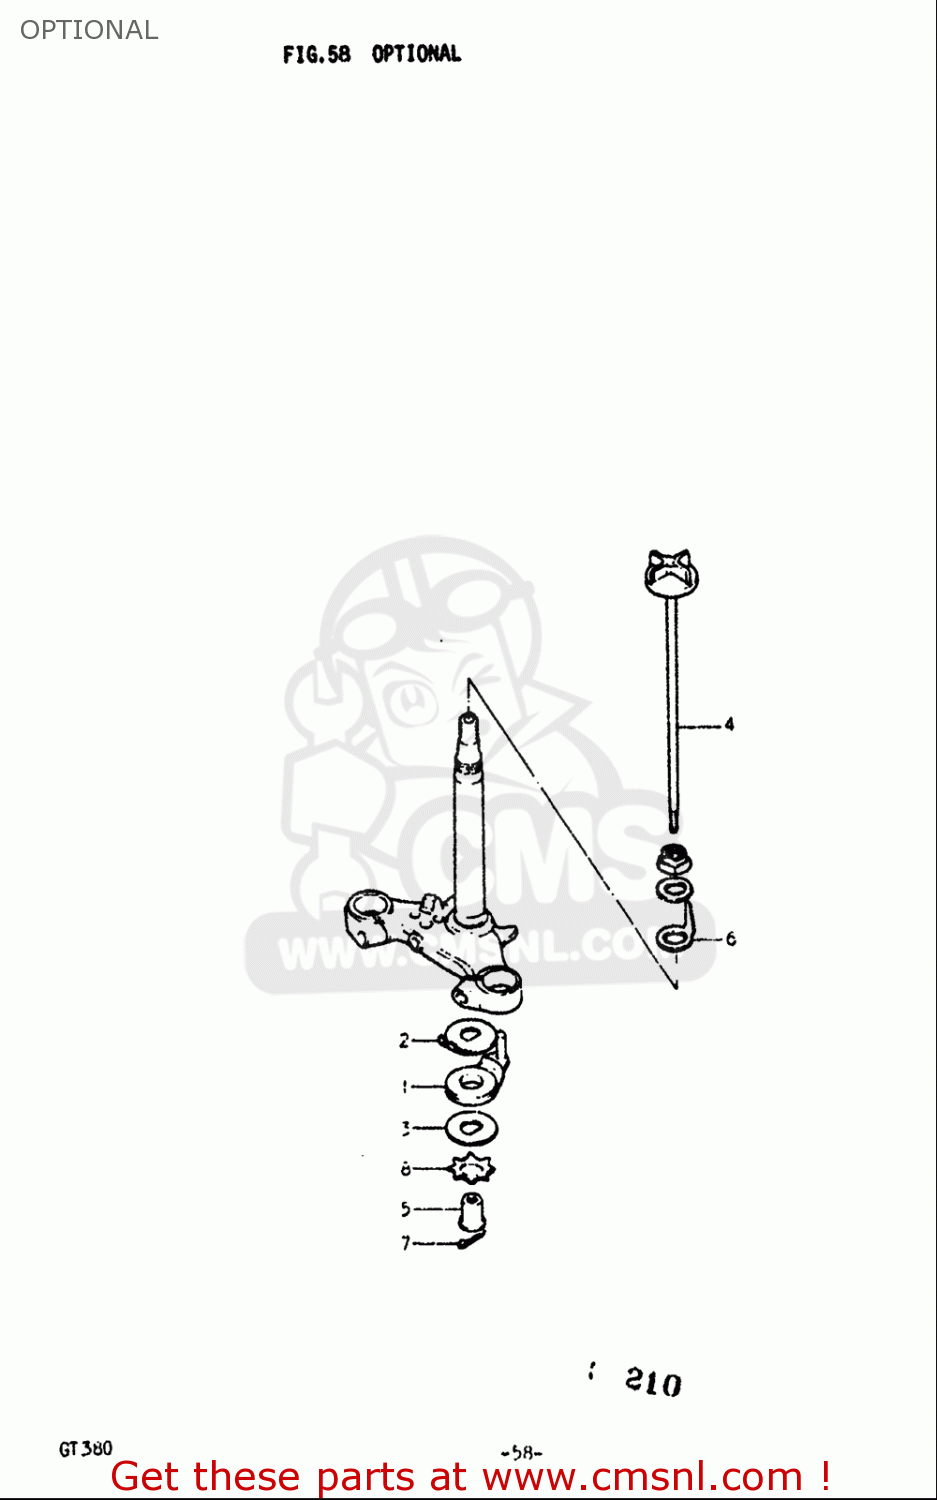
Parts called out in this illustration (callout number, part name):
5	HUB,HANDLEBAR DAMPER S
7	CLIP
8	SPRING, DAMPER ADJUST
